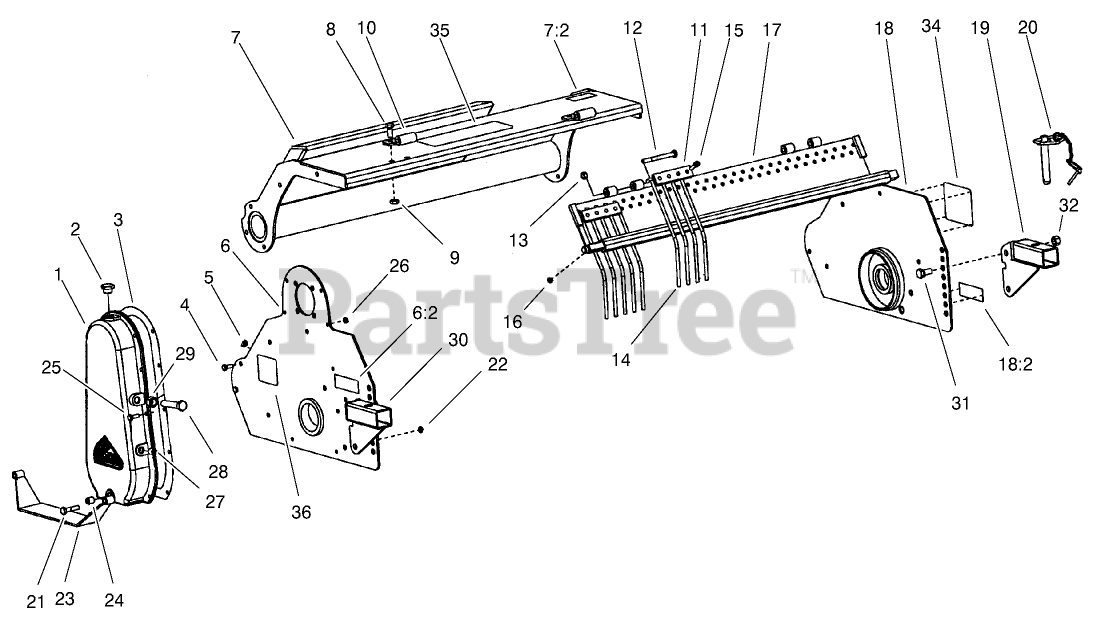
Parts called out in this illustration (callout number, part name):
1	CASE-CHAIN
3	GASKET-CORK
4	SCREW
5	NUT
6	LEFT SIDE ASM
6:2	DECAL-DANGER
7	FRAME CHASSIS ASM
7:2	DECAL-WARNING
9	NUT-LOCK
11	FLANGE
12	SCREW-HH
13	NUT
14	ROD-SCREENING
15	BOLT-HSH
16	NUT-LOCK, NI
17	PLATE-ROD, SCREENING
18	RIGHT SIDE ASM
18:2	DECAL-DANGER
19	PLATE-FITTING, RIGHT
20	PIN-DRIFT
21	SCREW
22	NUT
23	PLATE-PROTECTOR
24	PLUG-BRASS
26	NUT-LOCK, NI
27	PLUG-BRASS
28	Screw-HH
30	PLATE-FITTING, LEFT
31	SCREW-HH
32	NUT-HEX
34	DECAL-DINGO
35	DECAL-DINGO, FRONT
36	DECAL-LOGO, DINGO
